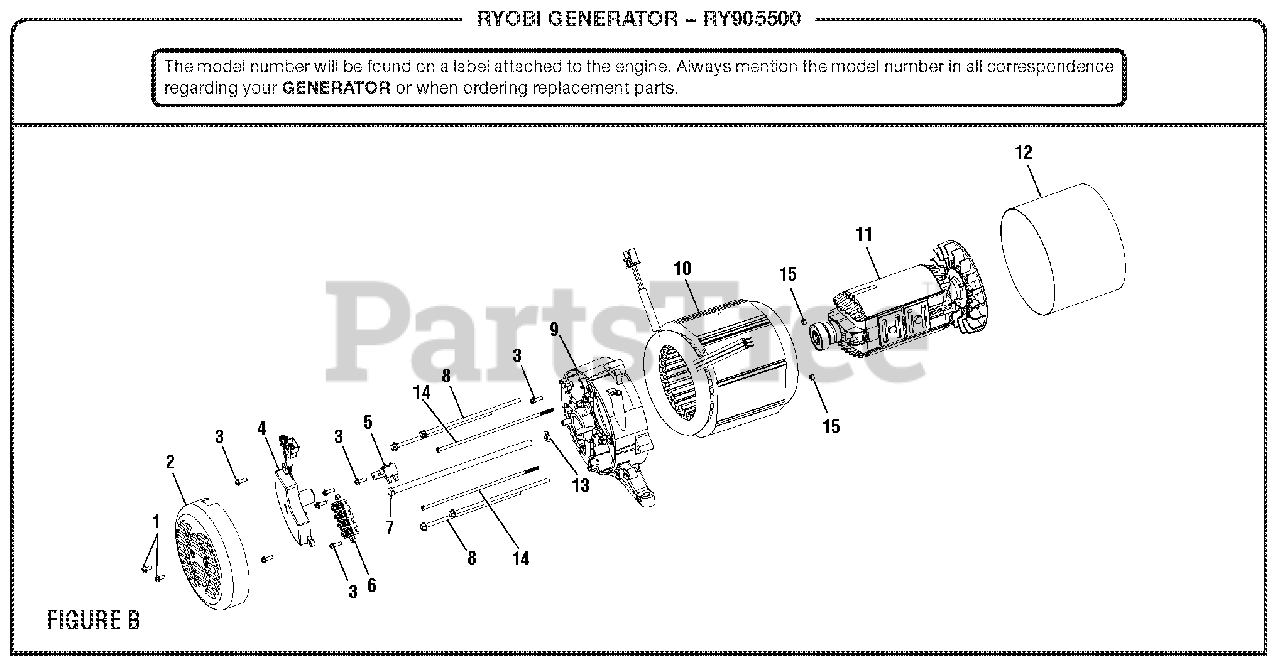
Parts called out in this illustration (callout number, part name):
1	Bolt (M5 x 12 mm, Hex Flange Hd.)
2	Brush Cover
3	Bolt (M5 x 16 mm, Hex Flange Hd.)
4	Automatic Voltage Regulator
5	Brush Assembly
6	Terminal Block
7	Rotor Bolt (M8 x 220 mm)
8	Stator Bolt (M6 x 180 mm)
9	Bearing Housing
10	Stator Assembly
11	Rotor Assembly
13	Rotor Washer
14	Bolt (M6 x 200 mm)
